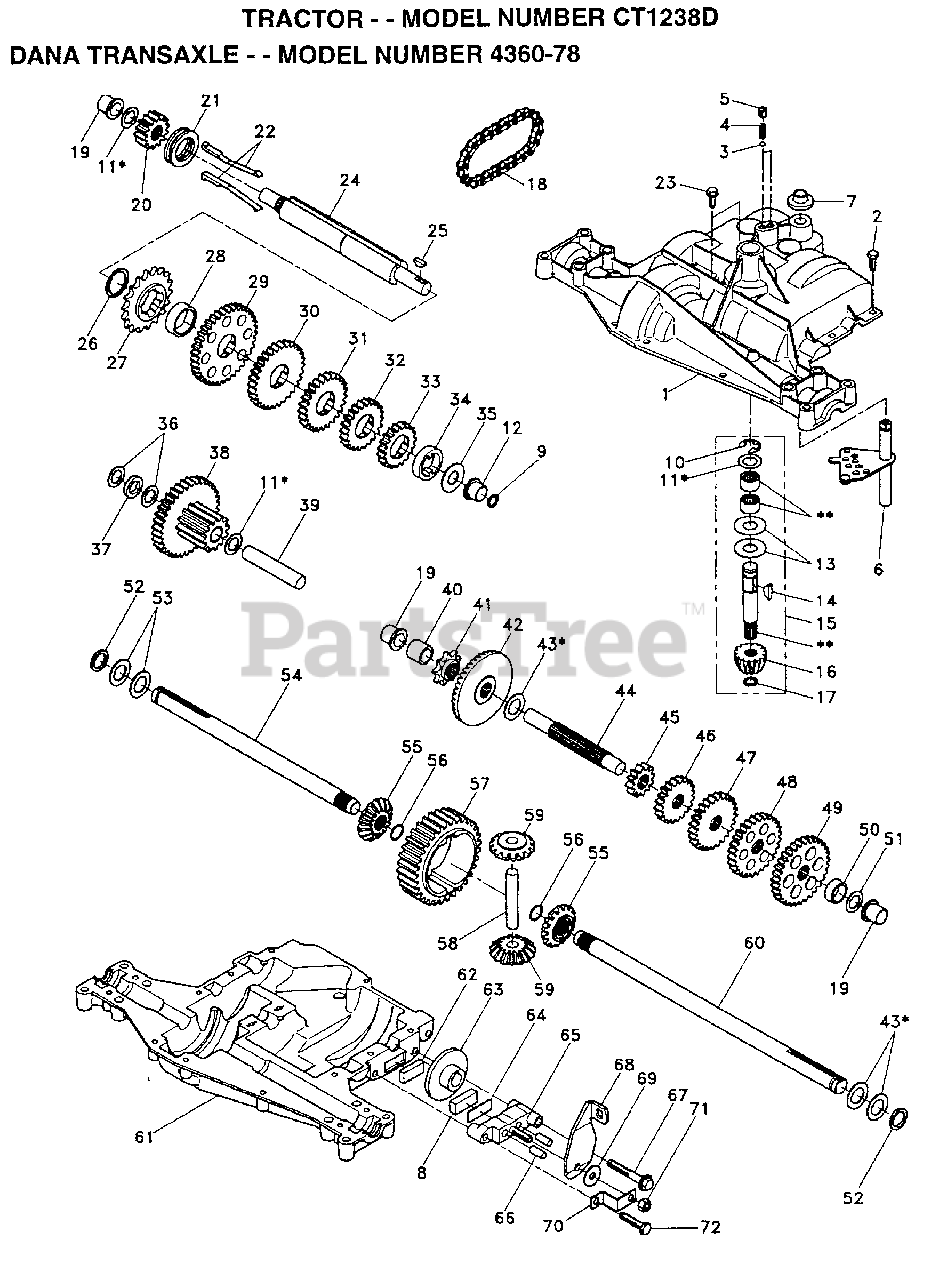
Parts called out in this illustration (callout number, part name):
1	HOUSING UPPER TRN
4	"SPRING, DETENT LT"
5	"SCREW, SET LT"
6	KIT SHIFTER ASM
7	SHIFTER BOOT
8	PUCK T
9	SEAL OIL DANA5416
11	ASM KIT SHIM 4689
13	WASHER T
14	KEY WOODRUFF-DANA
15	AS KIT INPUT SHFT
16	PINION 14T T
17	"RING,RETAINING LT"
18	"CHAIN,24 PTCH LT"
19	BEARING.FLNG.5510
20	GEAR SPUR 14 TTH
21	COLLAR CLUTCH
22	ASM KIT CLTCH KEY
23	SCREW TAP W/SEAL
24	SHAFT INTERM DANA
25	WOODRUFF KEY
26	"RING,RETAINING LT"
27	SPROCKET 18T T
28	SPACER YT
29	GEAR SPUR 37 TTH
31	GEAR 25T LT
32	GEAR SPUR 22 TT
33	SPUR GEAR 19T
34	SPACER
35	"WASHER, PLAIN LT"
36	WASHER 025
37	SPACER
38	ASSM GEAR COMB
39	SHAFT IDLER
40	SPACER T
41	SPROCKET 9T LT
43	ASM KIT SHIM
44	SHAFT T
45	GEAR SPUR 12 TTH
47	"GEAR, SPUR 25T LT"
48	GEAR 28T T
49	"GEAR, SPUR 31T LT"
51	WASHER 060
52	NEOPRENE WASHER
53	WASHER 031
55	GEAR 15T T
56	"RING,RETAINING LT"
58	SHAFT T
59	GEAR 1ST T
61	HOUSING LOWER TNS
62	PUCK T
63	BRAKE DISC. T
64	SPACER LT
66	PIN T
69	WASHER LT
71	NUT.LOCK.5/16-24
72	"SCREW, TAPPING LT"
